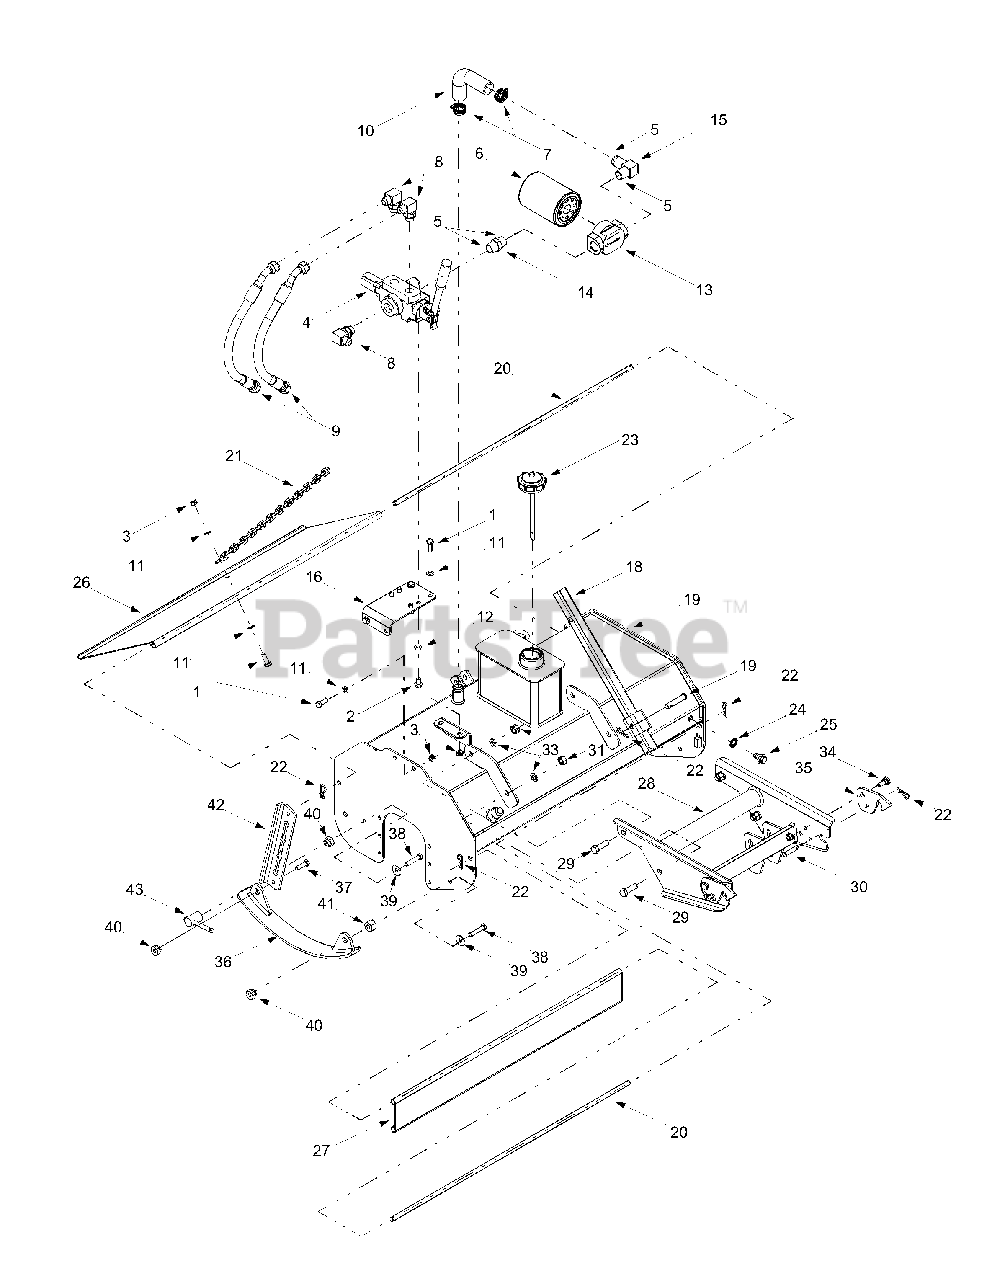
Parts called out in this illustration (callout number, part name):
1	Hex Cap Screw, 3/8-16 x 1.0
2	Shoulder Screw, 3/8-16 x .625
3	Hex Lock Nut, 3/8-16
4	Energy Hydraulic Valve
5	Locktite Hydraulic Sealant
6	Oil Filter
7	Adjustable Hose Clamp
8	90° Hydraulic Adapter, 7/8
9	Hydraulic Hose, 7/8-14
10	90° Hydraulic Hose, 1.37 x 1.0
11	Flat Washer, .375 x .738 x .063
12	Lock Washer, 3/8
13	Filter Housing
14	Hydraulic Adapter, 3/4 x 3/4
15	90° Hydraulic Adapter, 3/4 x 1.0
16	Valve Mounting Bracket
19	Clevis Pin, .50 x 2.0
20	Shield Pivot Rod
21	Chain, 24.37"
22	Internal Cotter Pin
23	Vented Tank Cap
24	Stat-O-Seal O Ring
25	Drain Plug
30	Clevis Pin, 3/8 x 1.75
31	Hex Nut, 1/2-13
32	Flange Lock Nut, 3/8-16
33	Lock Washer, 1/2
34	Shoulder Screw, .50 x .27, 3/8-16
35	Hitch Latch
36	Skid Bracket Assembly
37	Hex Cap Screw, 3/8-24 x 1.0
38	Hex Cap Screw, 3/8-24 x 1.75
39	Bell Washer, .396 x 1.14 x .095
40	Shoulder Nut, 3/8-24
41	Spacer, 1.0 x .380 x .64
42	Skid Adjuster Bracket
43	Adjuster Crank
